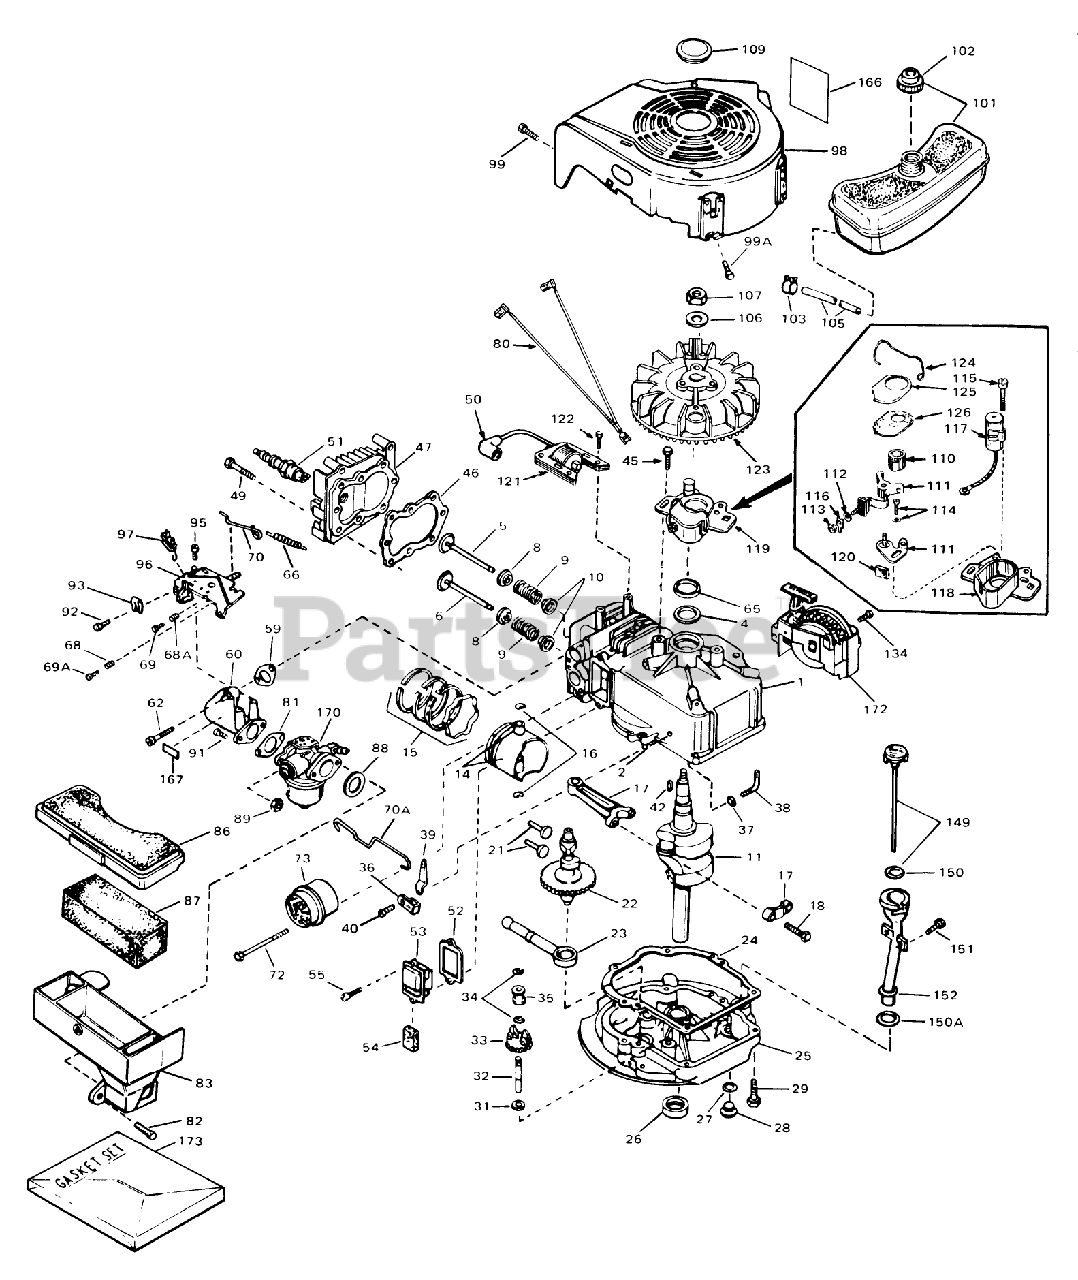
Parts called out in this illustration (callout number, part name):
1	Cylinder Assembly (Incl. Nos. 2 4)
2	Pin-Dowel
4	Seal-Oil
5	Valve, Intake (Incl. Ref. #38, 39 40) (Std.)
5	Valve, Exhaust (1/32" Oversize) (Incl. Nos. 8, 9 10)
6	Valve, Exhaust (Standard) (Incl. Nos. 8, 9 10)
6	Valve, Exhaust (1/32" Oversize) (Incl. Nos. 8, 9 10)
8	Cap-Upper Valve Spring
9	Spring-Valve
10	Cap-Valve, Spring
11	Crankshaft
14	Piston, Pin Ring Assy. (Std.) (Incl. Ref. #15 16)
14	Piston, Pin Ring Assy. (.010 Oversize) (Incl. Ref. #15 16)
14	Piston, Pin Ring Assy. (.020 Oversize) (Incl. Ref. #1516)
15	Piston Ring Set Std.
15	Piston Ring Set .010 O.S.
15	Piston Ring Set .020 O.S.
16	Ring-Retaining, Piston Pin
17	Rod Assy., Connecting (Incl. Ref. #17)
18	Bolt-Rod, Connecting
21	Lifter-Valve
22	Camshaft(Mech.Comp. Release)
23	Oil Pump ASM
24	Gasket, Mounting
25	Flange Assy., Mounting (Incl. Ref. #26thru 30)
26	Seal Oil
27	Gasket-Oil Drain
28	Plug Oil Drain
29	Screw (1/4-20 x 1-1/4)
31	Washer-Flat
32	Shaft-Governor
33	Governor Gear ASM
34	Ring-Retaining
35	Spool-Governor
36	Clamp-Lever, Governor
37	Washer-Flat
38	Rod, Governor (Incl. No. 36)
39	Lever, Governor
40	Screw
42	682488 LB GRASS HI-
45	Screw
46	Gasket-Cylinder Head
47	2025A67 ADD.ASSEMBL
49	Screw (5/16-18x1-1/2)
50	Cover-Spark Plug
51	Plug, Spark (J17LM or equiv.)
51	Plug, Spark (Champion RCJ-8)
52	Gasket Breather
53	Breather Assembly (Incl. Nos. 52 84)
54	Element-Breather
55	Screw
59	Gasket, Intake
60	Pipe, Intake
62	Screw (1/4-20 x 1)
65	Gasket Stator
66	Spring Governor
68	61709/GIL1515A/95-5
68A	Spring-Compression
69	Screw
69A	Screw
70	2035A67 ADD.ASSEMBL
70A	Link-Throttle
72	Screw
73	Muffler Kit (Incl. Ref. #72)
80	Wire Ground
81	Gasket
82	Screw
83	Body, Air Cleaner
86	Cover Air Cleaner
87	Filter-Air Cleaner
88	Gasket-Cleaner, Air
89	Nut and Lock Washer (1/4-28)
92	Screw (10-32 x 3/8)
93	Conduit
95	Screw (10-24 x 9/16)
96	Control Assy.-Remote Speed (Incl. Ref. #69 thru 72 76)
97	Terminal
98	Housing, Blower
99	Screw (10-24 x 9/16)
99A	Screw
101	Tank, Fuel
102	Cap, Fuel
103	Clamp-Line, Fuel
105	Fuel Line
106	Washer-Belleville
107	Nut-Flywheel
109	Plug, Screen
110	Cam-Breaker
111	Breaker Assy.
112	Washer
113	DECAL
114	Breaker Screw
115	Condenser Screw
116	Terminal, Ground
117	Condenser
118	Stator Plate
119	Stator Plate Assy. (incl. Nos. 107, 111 thru 118 120)
120	Felt,Cam Wiper
121	Lamination Coil Assy. (Incl. No. 42)
122	Screw
123	FIywheel
124	Spring Breaker Box
125	Cover-Dust
126	Gasket-Dust Cover
134	Screw (1/2-20x5/8)
149	Dipstick-Oil (Incl. Ref. #112)
150	O-Ring
150A	Gasket
151	Screw (10-32 x 1/2)
152	Tube-Oil Fill
166	Decal, Instruction
167	Decal-Primer
170	Carbu retor (Incl. Ref. #81)
172	Starter-Sidemount
173	Gasket Set
